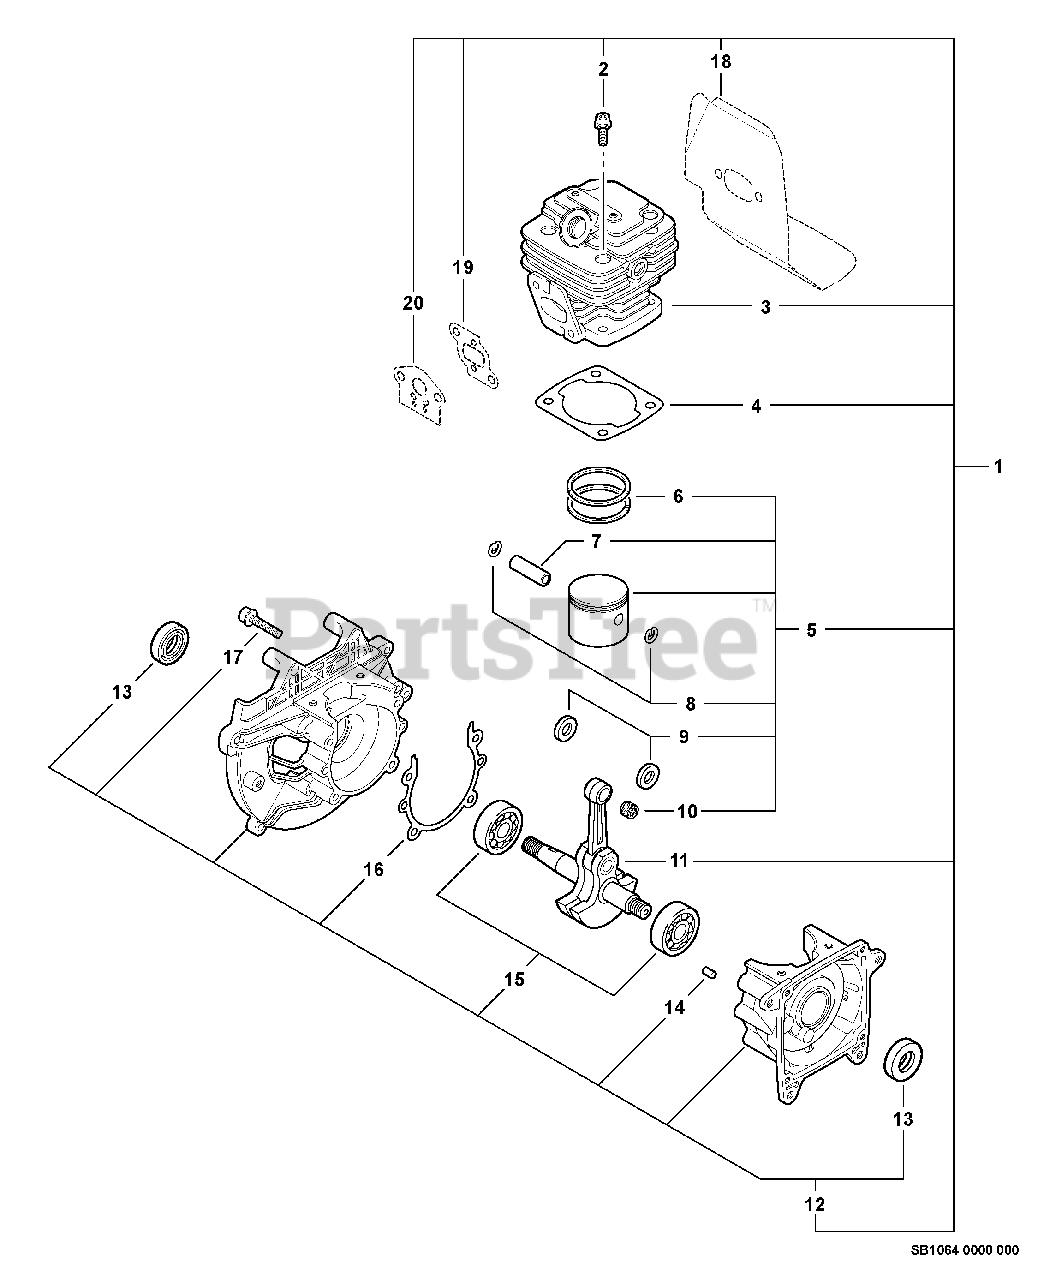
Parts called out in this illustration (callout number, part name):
1	SHORT BLOCK
2	BOLT 5×20
3	CYLINDER
4	GASKET, CYLINDER
5	PISTON KIT
6	RING, PISTON
7	PIN, PISTON
8	RING, SNAP
9	WASHER, THRUST
10	BEARING, NEEDLE 9
11	CRANKSHAFT ASSY
12	CRANKCASE KIT
13	SEAL, OIL 12
14	PIN, LOCATING 4×8
15	BEARING, BALL - 6201 C3
16	GASKET, CRANKCASE
17	BOLT 5×30
18	SHIELD, EXHAUST
19	GASKET, INTAKE
20	GASKET, INTAKE
